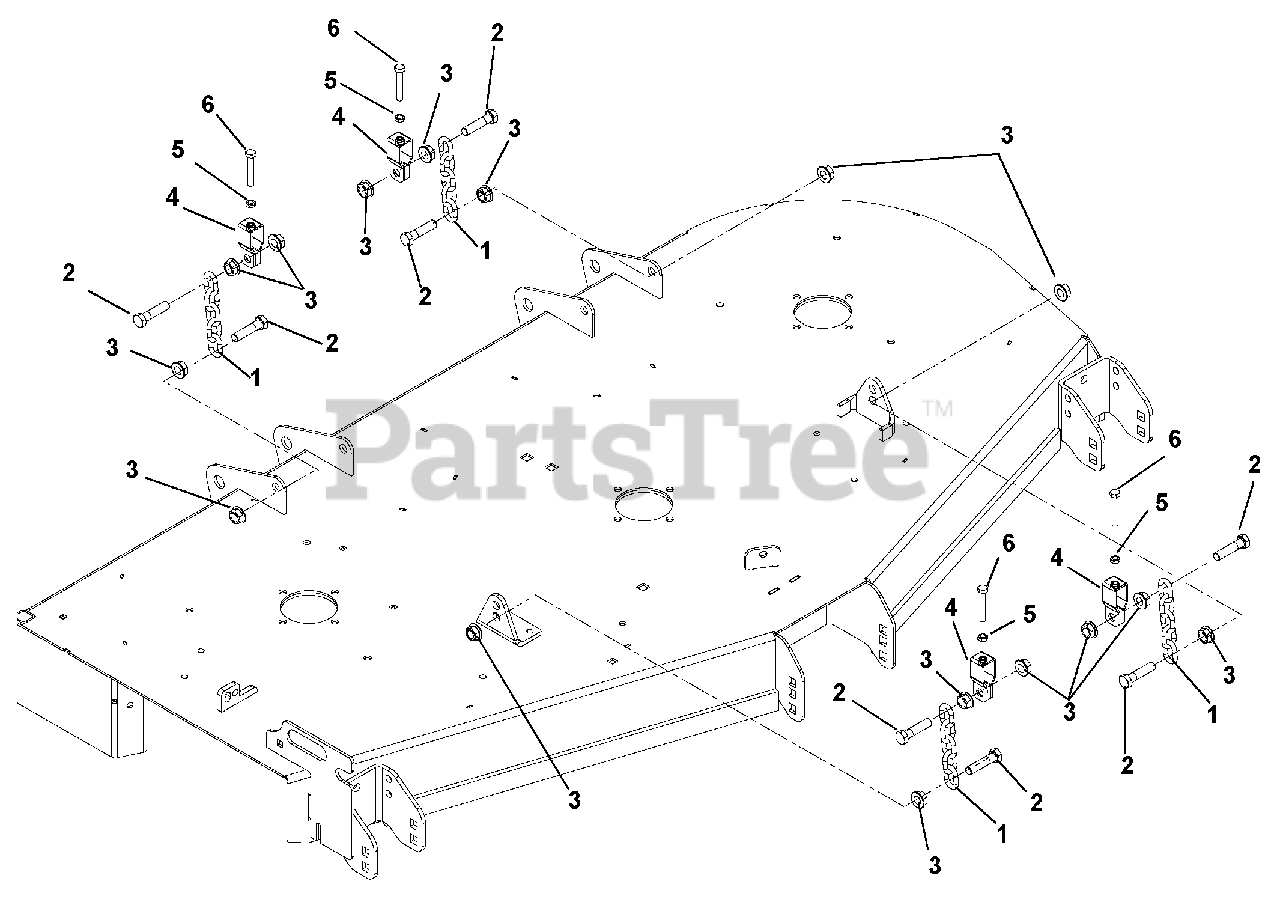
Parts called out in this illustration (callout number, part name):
1	CHAIN, LINK
2	BLT, HEX M12-1.75X50 CLS8.8 YZ
3	NUT-SPNLK-FLG M12-1.75 YZ
4	BRKT, DECK LEVELING
5	NUT- JAM .312-18 YWZC
6	BLT-HEX .312-18X2.00 FTH GR5YZ
